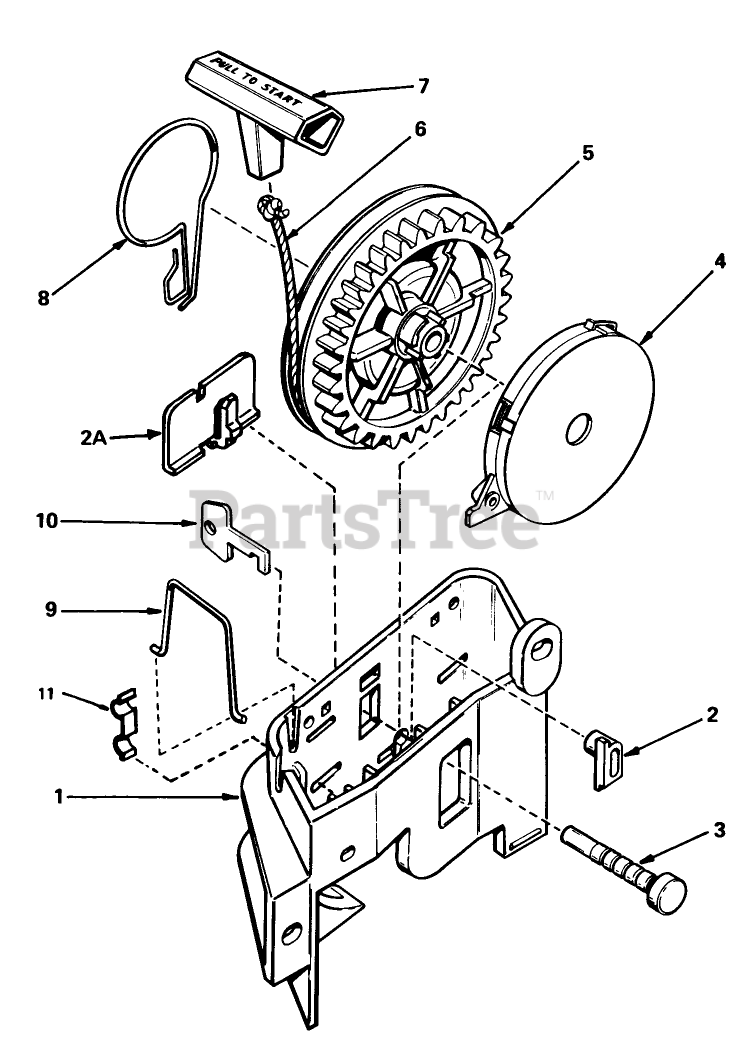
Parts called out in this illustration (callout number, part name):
1	Bracket Starter
2	Pawl, Locking Not used on all engine models)
2A	Clip, Starter Bracket (Used On Starters Not Equipped With Pawl, Ref. No. 2)
3	Pin-Pulley
4	Spring Assy., Rewind (Incl. Ref. #3)
5	Pulley
6	Rope Starter (Length 65" 9/64" Dia.)
7	Handle-Starter
8	Brake
9	Clip-Rope
10	Key (Not Used On All Engine Models
11	Washer-Thrust
